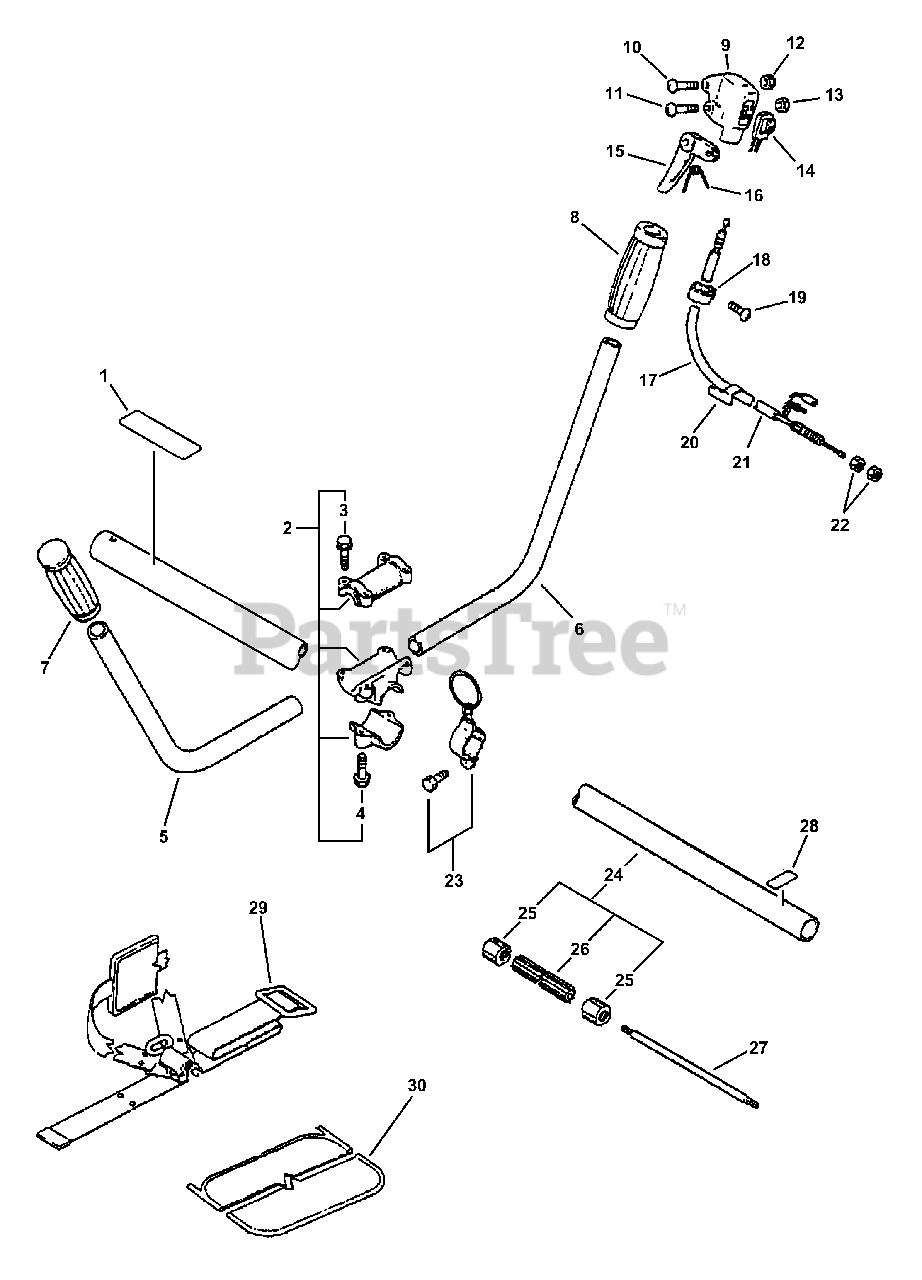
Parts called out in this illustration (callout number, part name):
1	LABEL, CAUTION
2	BRACKET KIT, HANDLE
3	BOLT - 5×25
4	BOLT - 6×30
5	HANDLE, LEFT
6	HANDLE
7	GRIP, HANDLE
8	GRIP
9	BODY, THROTTLE CONTROL
10	SCREW 5×25
11	SCREW
12	NUT, LOCK M5
13	NUT M5
14	IGNITION SWITCH ASSY
15	TRIGGER, THROTTLE
16	SPRING
17	CABLE, THROTTLE
18	CLAMP
19	SCREW 5×10
20	BRACKET
21	TUBE
22	NUT
23	HANGER SET, HARNESS
24	MAIN PIPE ASSY 25×1500
25	STOPPER
26	LINER, FLEXIBLE 21.6×1420
27	DRIVESHAFT - FLEXIBLE L= 1522
28	LABEL - ALIGNMENT
29	SHOULDER STRAP ASSY
30	PAD, HIP
